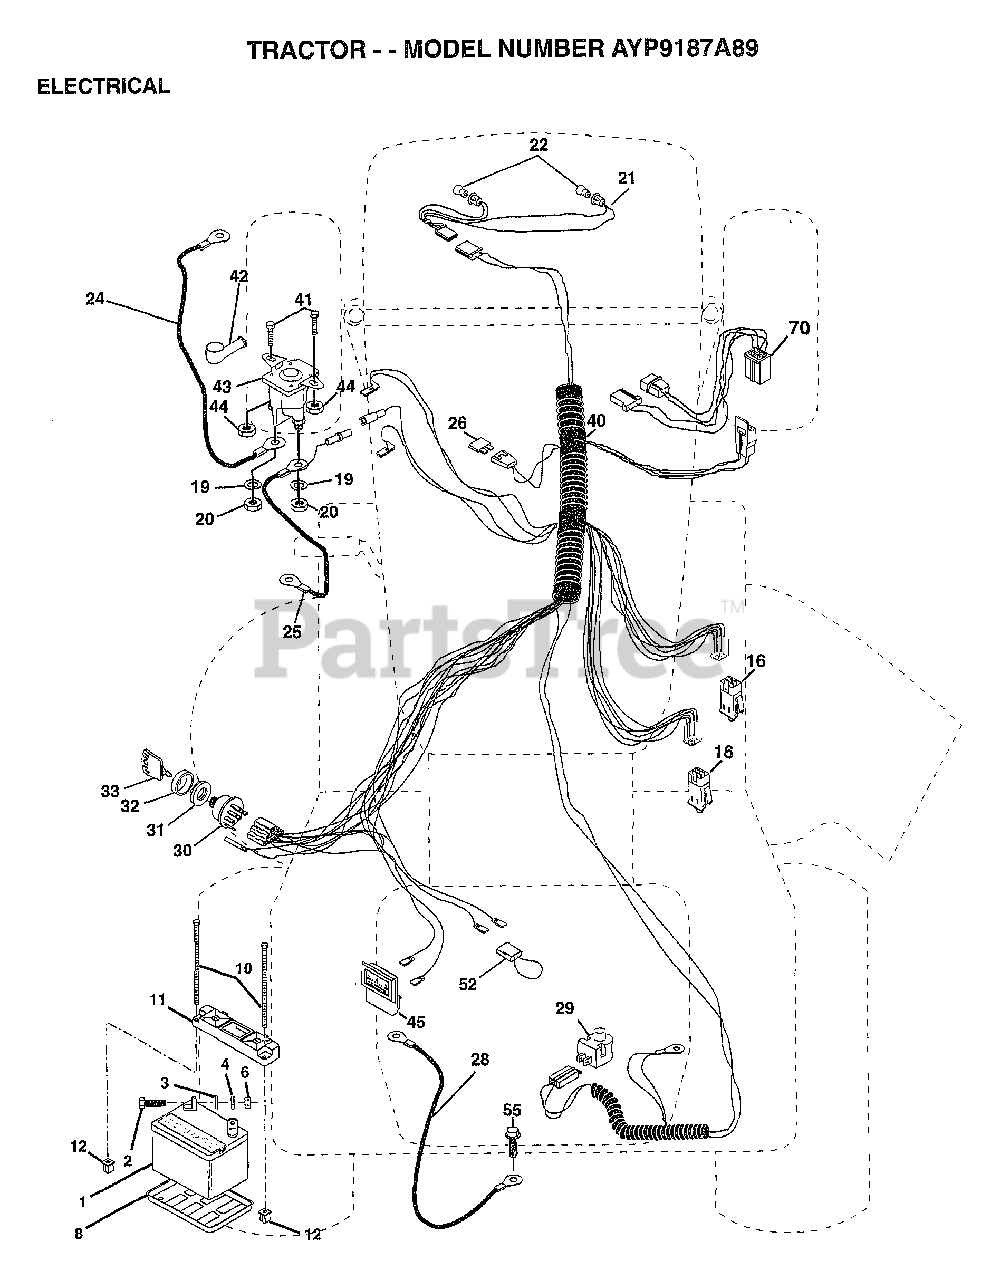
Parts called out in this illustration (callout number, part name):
3	WASHER
4	LOCKWASHER
8	"TRAY T, BATTERY"
11	HOLDDOWN BATTERY
16	SWITCH INTERLOCK
20	NUT
21	"HARNESS,LIGHT SOC"
22	HEADLAMP BULB
24	"CABLE T, BATTERY"
25	CABLE.6GA.22W/16W
26	FUSE HYT
28	CABLE.GRND.6GA.21
29	SWITCH SEAT
30	SWITCH IGN 4POS
31	NUT IGNITION
32	COVER KEY SWITCH
33	KEY
40	HARNESS-IGNITION
41	BOLT HXHD FIN
44	NUT HXKEP 1/4X20
52	PROTECTION LOOP
55	SCREW LT
70	HARNESS.ENG.DUAL
